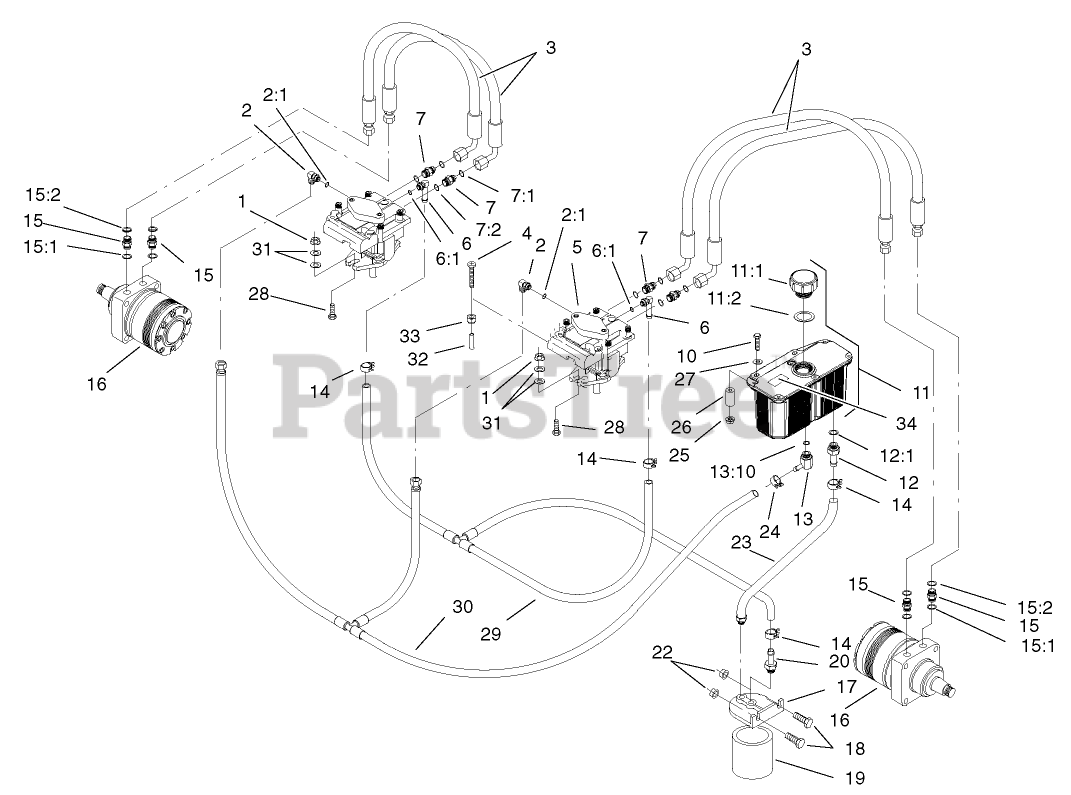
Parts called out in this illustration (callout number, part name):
1	NUT-HHF, WHIZ
2	FITTING-90 DEG
2:1	O-RING
3	HOSE-PRESSURE, HIGH
6	FITTING
6:1	O-RING
7	FITTING-STRAIGHT
7:1	O-RING
7:2	O-Ring
10	SCREW-HH
11	Reservoir-HYD
11:1	CAP-RESERVOIR, HYD
11:2	GASKET-CAP
12	ADAPTER-STRAIGHT
12:1	O-RING
13	Elbow-45deg.
13:10	O-Ring
14	Clamp-Hose
15	Fitting-Straight
15:1	O-RING
15:2	O-Ring
16	HYD MOTOR ASM
17	HEAD-FILTER
18	SCREW-HH
19	FILTER-OIL, HYD
20	Adapter-Straight
22	NUT-HF
23	HYD Hose ASM
24	Clamp-Hose
25	NUT-HF
26	Spacer
27	WASHER-FLAT
28	SCREW-HH
29	HYD Hose ASM
30	HYD Hose ASM
31	WASHER-FLAT
32	GRIP-VALVE, DUMP
33	NUT-LOCK, NI
34	DECAL-TANK, HYD
